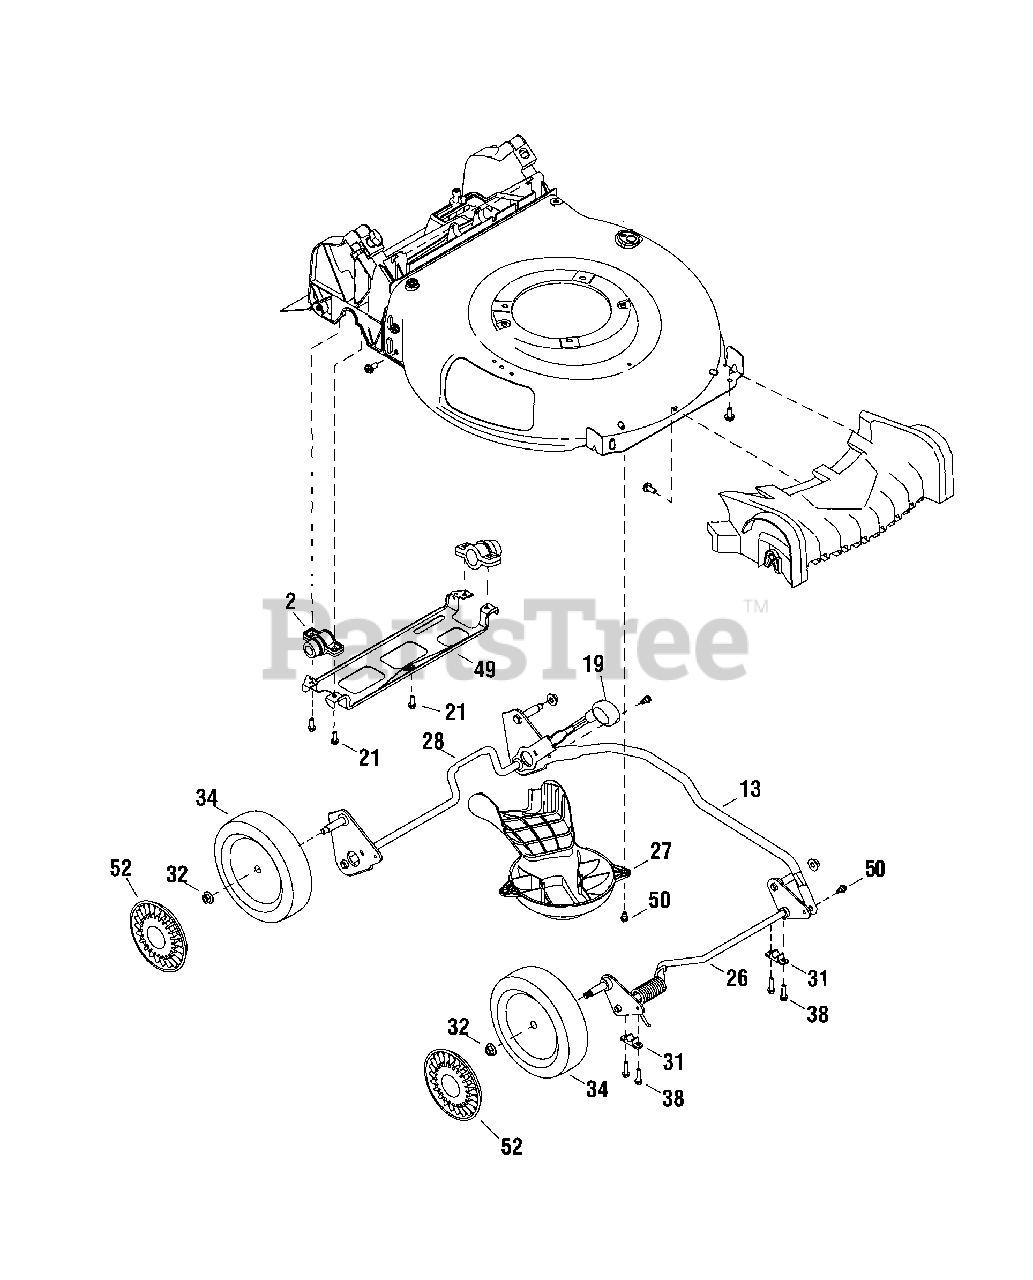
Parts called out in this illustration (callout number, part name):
2	ASSEMBLY, Bearing
13	BRACKET, Cross
19	KNOB, Adjustment Lever
21	SCREW, 1/4-15 x 1-1/4
26	AXLE ASSEMBLY, Front
27	BAFFLE, Engine
28	AXLE ASSEMBLY, Rear
31	BUSHING, Lock
32	NUT, Hex Flange, Nylock, 3/8-16
34	WHEEL, 8 x 2, Black
38	SCREW, 1/4-15X3/4, Self-Tapping, BZ
49	SUPPORT, Rear Bracket
50	BOLT, Shoulder, 1/4-20 x 1/2
52	HUBCAP, Front, 8" Silver
